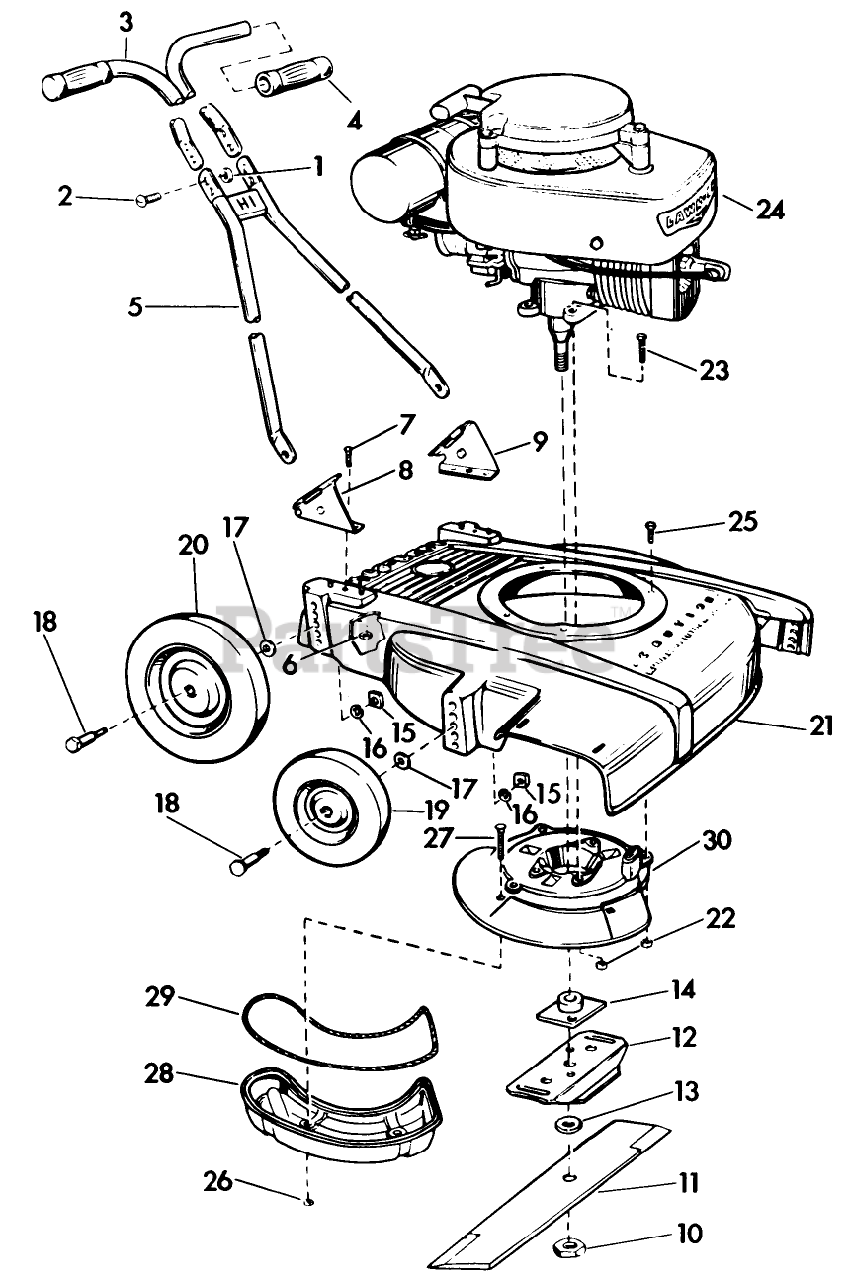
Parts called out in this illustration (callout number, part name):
1	STOP NUT
10	NUT-BLADE
11	Blade-21"
14	PLATE AND COLLAR ASM
16	WASHER, LOCK
21	Housing-18"
21	Housing-21"
26	LOCKNUT E
